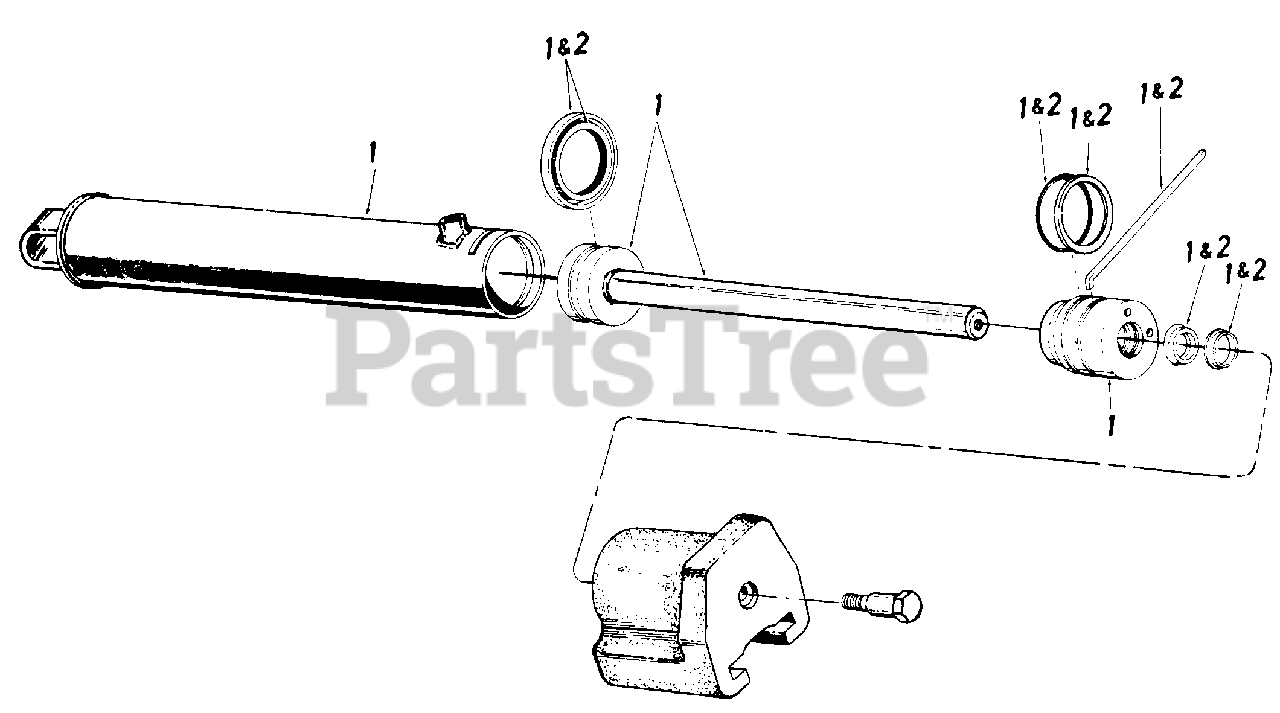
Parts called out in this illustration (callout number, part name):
1	CylinderAss'y. Comp.
1	CylinderAss'y. Comp
2	3-1/2" Cyl. Kit "O"-RingSet
2	4" Cyl. Kit "O"-Ring Set
